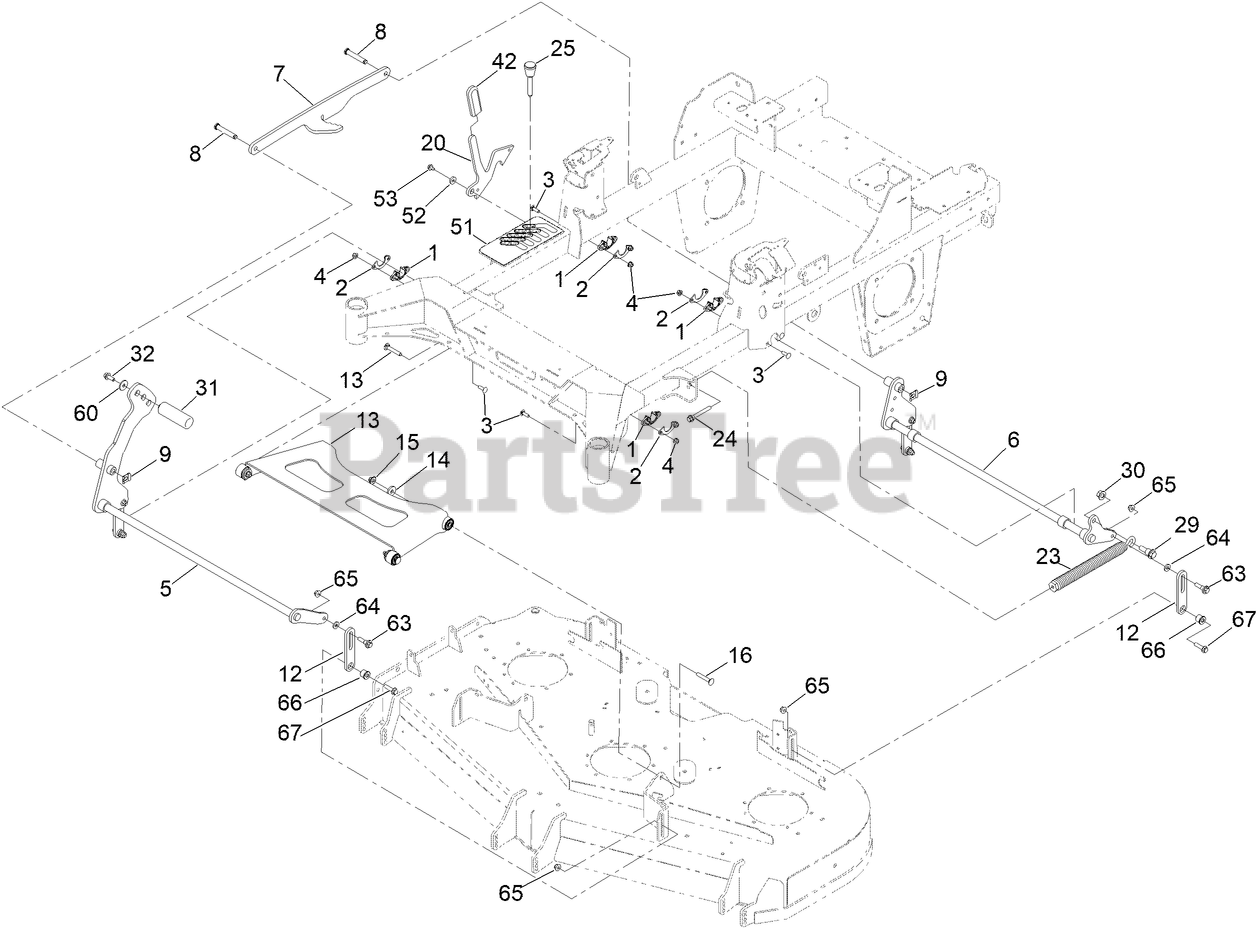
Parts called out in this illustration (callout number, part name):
1	BEARING-FLANGE
2	GUSSET-LIFT, DECK
3	SCREW-CARR
4	NUT-HF, NI
5	DECK LIFT SHAFT ASM [BLACK]
6	DECK LIFT SHAFT ASM [BLACK]
7	LINK-LIFT
8	PIN-CLEVIS
9	CLIP-PIN
12	LINK-LIFT, DECK
13	ASM-DECK STRUT W/ BUSHINGS
14	WASHER
15	NUT-FLANGE, NI
16	SCREW-CARR
20	PLATE-TRANSPORT LOCK
23	SPRING-EXTENSION
24	BOLT-SHOULDER
25	PIN-HOC
29	SCREW-SHOULDER, HHF
30	NUT-LOCK
31	PEDAL-FOOT LIFT
32	SCREW-HHF
42	GRIP-LEVER
51	DECAL-HOC
52	SPACER
53	SCREW
60	WASHER
63	BOLT-SHOULDER
64	SPACER
65	NUT-HF, NI
66	BUSHING-DECK LIFT
67	SCREW-HHF
